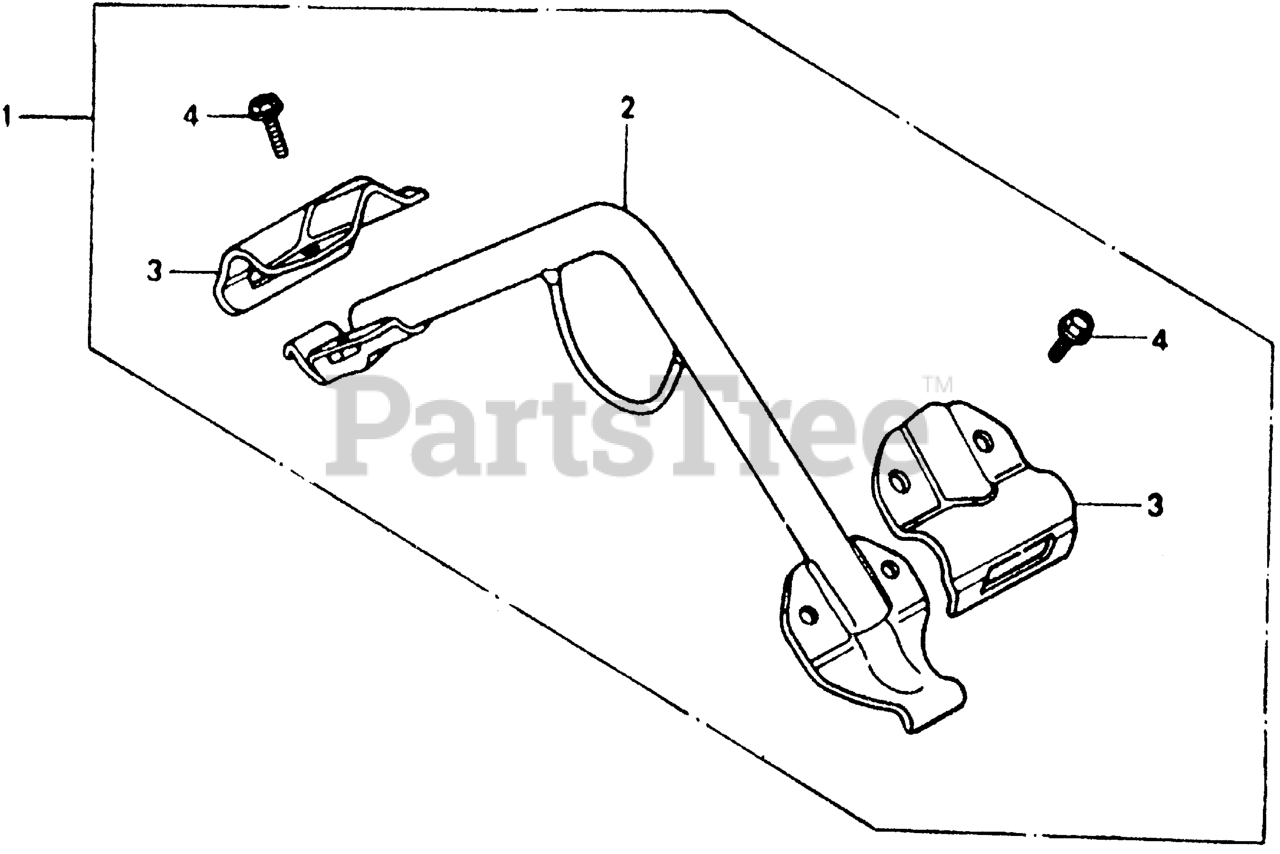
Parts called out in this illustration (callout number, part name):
1	HANGER KIT Use up to Frame SN 1081652.
1	HANGER KIT
2	HANGER Use up to Frame SN 1081652.
2	HANGER
3	BRACKET, HANGER (UPPER)
4	BOLT, FLANGE (8X16) Use from Engine SN 1000016.
